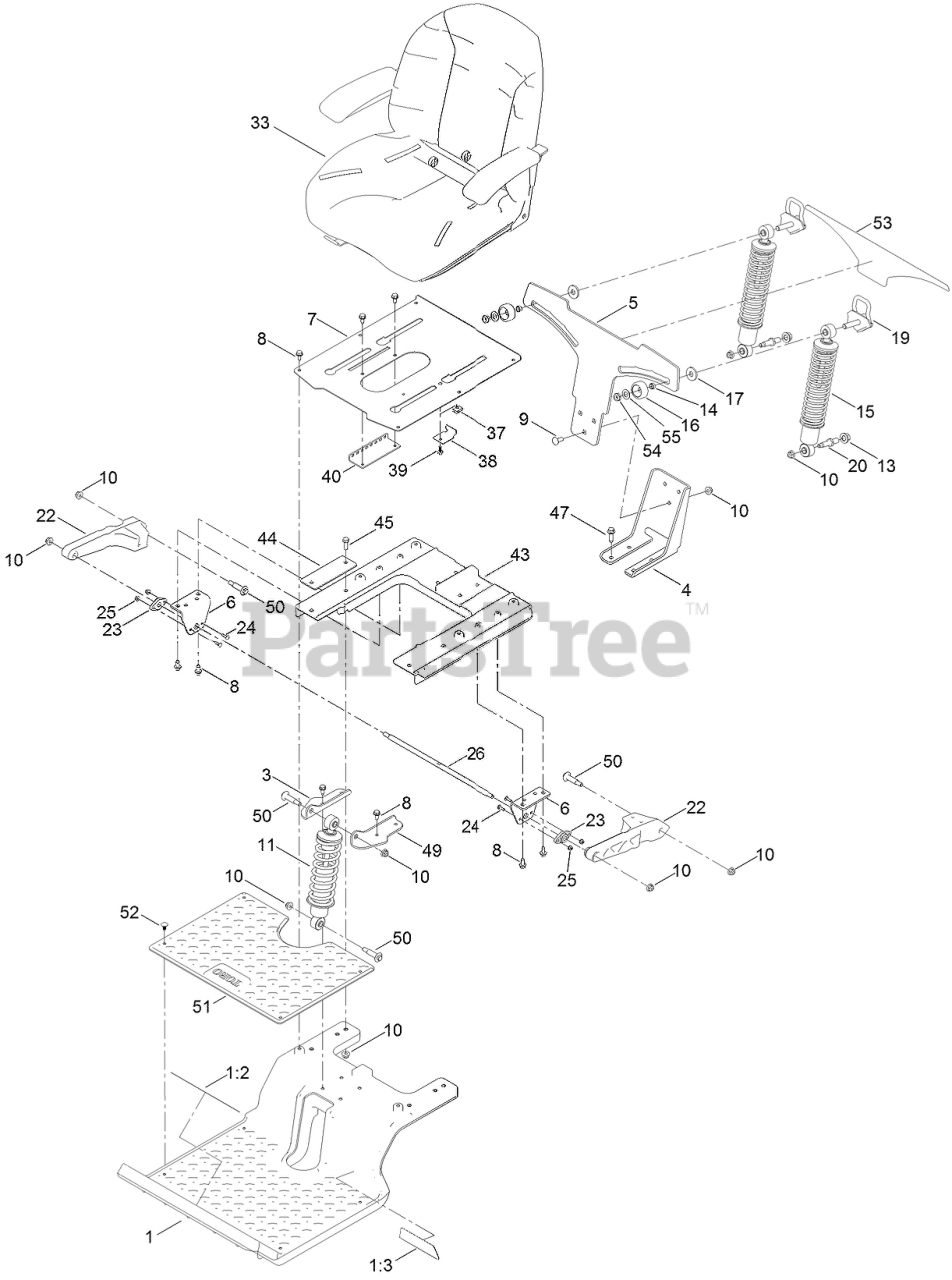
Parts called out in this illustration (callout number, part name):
1	SUBFRAME-FRONT
1:2	DECAL-DANGER
3	BRACKET-SHOCK MOUNT, UPPER (RH)
4	BRACKET-MOUNT, LOWER
5	BRACKET-MOUNTING, SHOCK
6	BRACKET-MOUNT, SWING ARM
7	PAN-SEAT
8	SCREW-HWHTF
9	SCREW-CARR
10	NUT-HF, NI
11	SHOCK ASM
13	NUT-LOCK
14	BEARING-SLEEVE
15	SHOCK/SPRING ASM
16	KNOB-LOCK, CAM
17	WASHER-PLASTIC
19	CAM LOCK ASM
20	BOLT-SHOULDER
22	TRAILING ARM
23	BEARING-FLANGE
24	SCREW-CARR
25	NUT-HF
26	ROD-PIVOT
33	SEAT ASM
38	BRACKET-STOP, SEAT
39	SCREW-HHF
40	BRACKET-LATCH, SEAT
43	SUBFRAME-REAR
44	PLATE-BACKER
45	SCREW-HH
47	SCREW-THD FORM HWH
49	BRACKET-SHOCK MOUNT, UPPER (LH)
50	BOLT-SHOULDER
51	FLOORMAT
52	PLUG-PLASTIC
53	DECAL-ADJUSTMENT, RIDE
54	NUT-HEX
55	WASHER-ADJUSTING
